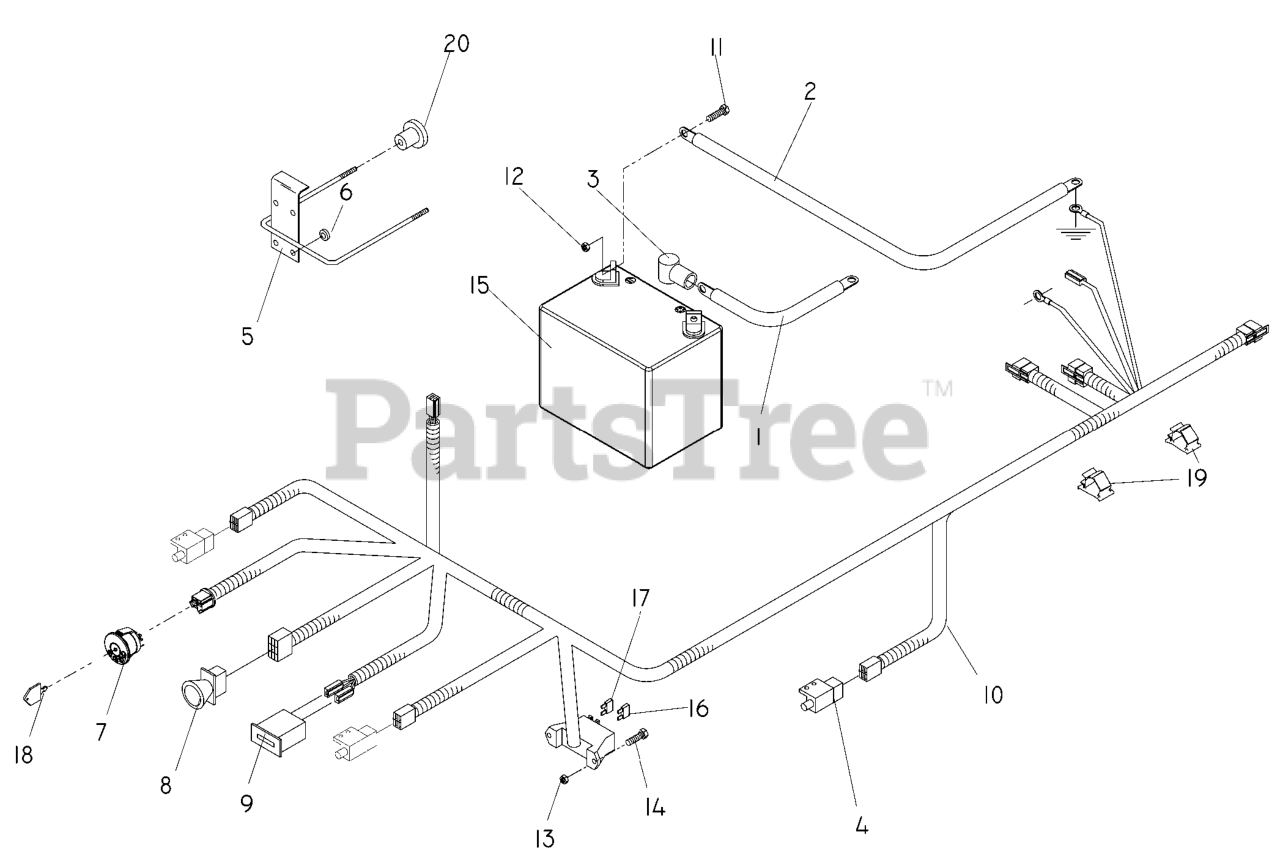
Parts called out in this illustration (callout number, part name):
1	POST.CABLE LONG
2	CABLE-NEGATIVE
4	SWITCH, BRAKE 3P
5	BATTERY HOLD DOWN
6	GROMMET, BUMPER
7	RP IGNITION SWITCH
8	SWITCH, PTO 10 AMP
9	HOUR METER
10	HARNESS, WIRING LZ/IZ
11	HCS 5/16C X 3/4
12	NUT 5/16 NYLOC
13	NUT 10-24 NYLOC
14	SCREW, #1--24 X 1/2 SLOTTED
15	BATTERY, 12 V 330 AMP
16	FUSE, 7.5 AMP 32 VOLT ATO
17	FUSE, 20 AMP 32 VOLT ATO
18	KEY
19	PUSH-MOUNT WIRE CLIP
